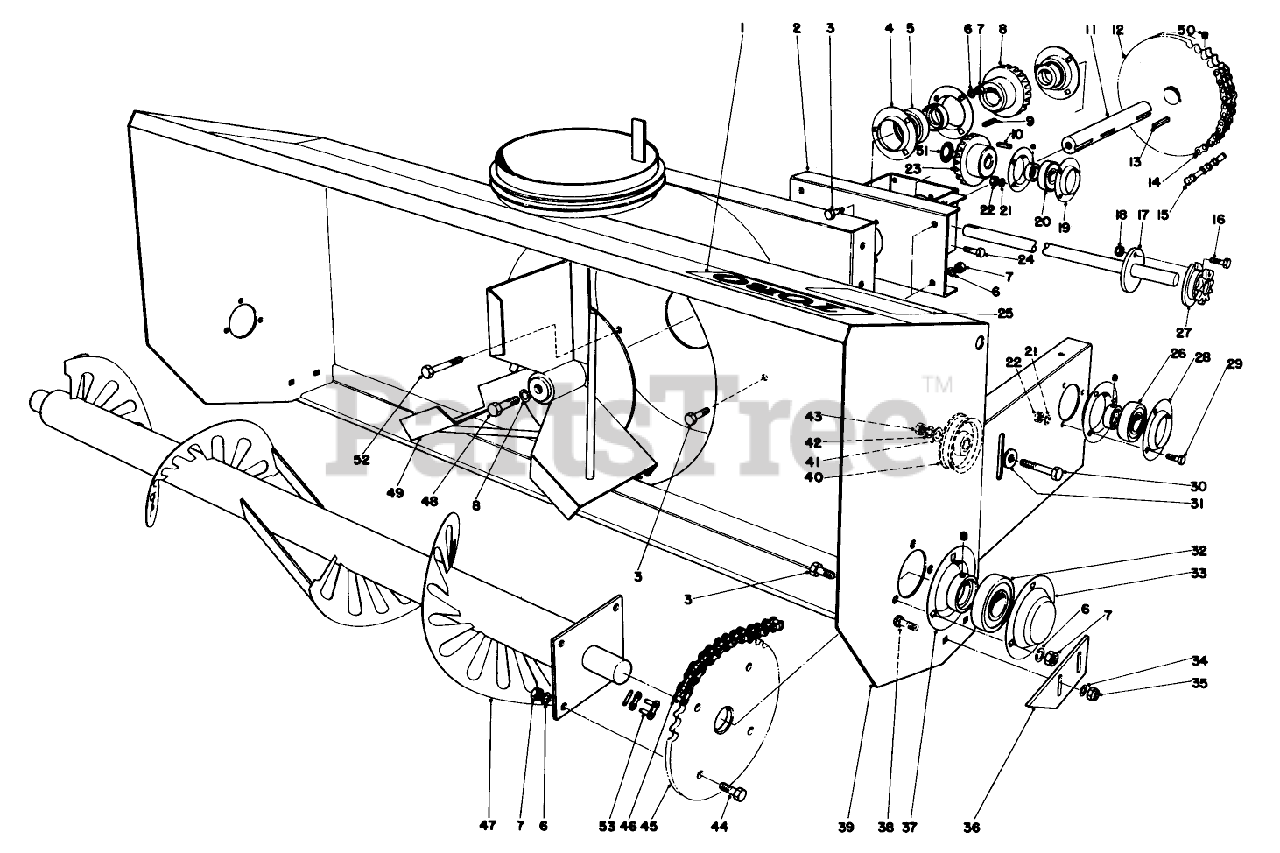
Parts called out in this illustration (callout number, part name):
1	Decal
2	Gear Case Mounting Bracket
3	SCREW-HH
4	BEARING-FLANGE
5	BEARING-BALL
6	WASHER-LOCK
7	NUT-HEX
10	KEY-SQUARE
11	Rotor Shaft
12	Sprocket
13	KEY-SQUARE
14	Roller Chain
15	Connecting Link
16	SCREW-HH
17	Cross Shaft
18	NUT-LOCK, NI
19	BRG FLANGE
20	BALL BRG W/COLLAR
21	WASHER-LOCK
22	NUT-HEX
24	SCREW-HH
25	Decal Caution
26	BALL BRG W/COLLAR
27	Auger Drive Sprocket
28	BRG FLANGE
29	SCREW-HH
30	SCREW-HH
31	WASHER-FLAT
32	BEARING-BALL
33	Flangette w/cap
34	WASHER-FLAT
35	NUT-LOCK, SIDE
37	BEARING-FLANGE
38	BOLT-CARR
39	Mold Board Assembly
40	Chain Idler
41	WASHER-FLAT
42	WASHER-LOCK
43	NUT-HH
44	SCREW-HH
45	Sprocket Auger Drive
46	Roller Chain
47	Auger Assembly
48	Capscrew
49	Rotor
50	SCREW-SET
51	Retainer Washer
52	SCREW-HH
53	LINK-CHAIN
